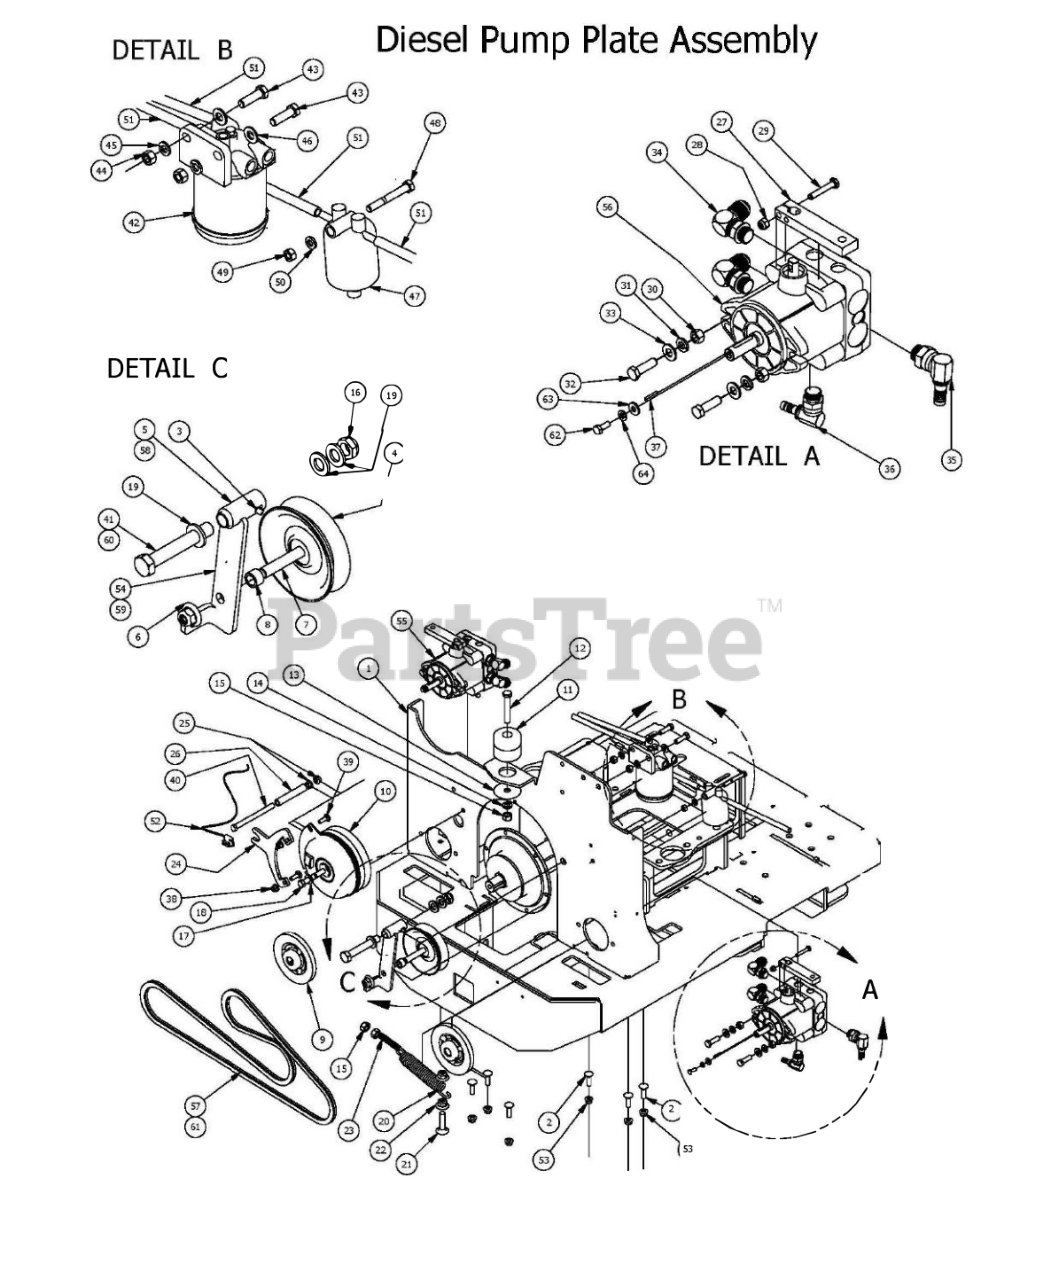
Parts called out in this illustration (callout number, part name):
1	Pump Plate Diesel
2	3/8" x 1 1/4" Carriage Bolt
3	1/4" Drive in Grease Fitting
4	4 3/4" Idler Pulley
5	Pump Idler Bracket only for 61" Deck
6	1/2-13 Nylon Flange Nut-Orange
7	1/2" x 3" Hex Bolt
8	1/2 x 1/2 Spacer
9	5" Pump Pulley
10	Clutch Assembly for Diesel
11	Armor Plated Mount-Rear Mount
12	1/2" x 3" Hex Bolt
13	Snubbing Washer
14	1/2" Lock Washer
15	1/2" Hex Nut
16	5/8" Nylock (1/2 Jam)
17	7/16" Lock Washer
18	7/16" x 2 3/4" Fine Thread Bolt
19	.630 ID x 1.122 OD x .142 THK Plastic Washer
20	Deck Idler Spring
21	1/2 x 2" Carriage Bolt
22	1/2-13 Nylon Flange Nut-Orange
23	1/2-13 x 2-1/2 All Thd Stud
24	Diesel PTO Engager Holder
25	3/8" Flange Nut
26	3/8 hose 4" long
28	1/4" Nylock Nut
29	1/4" x 1 1/2" Bolt
30	3/8" Hex Nut
31	3/8" Lock Washer
32	3/8" x 1 1/2" Hex Bolt
33	3/8" Flat Washer
34	90 Degree Adaptor 6801-L-8-8 Fitting
35	90 Degree Fitting 1/2" x 3/4" 4601-8-8
36	90 Degree Fitting 3/8" X 9/16"-4601-6-6
37	5mm x 1.25" Key
38	5/16" Flange Nut
39	5/16" x 1" Carriage Bolt
40	3/8-16 x 5 Hex Bolt - Grade 5
41	5/8" x 4" Hex Bolt 61" Deck only
42	Fuel Filter
43	3/8" x 1 1/4" Hex Bolt
44	3/8" Hex Nut
45	3/8" Lock Washer
46	3/8" Flat Washer
47	Caterpillar Fuel Bowl Kit
48	5/16" x 2 1/2" Bolt
50	5/16" Lock Washer
51	5/16" fuel line hose
52	Clutch Pigtail
53	3/8" Nylock Flange Nut
54	Pump Idler Assembly Components 3,4,5,6,7,8, only for 61" Deck
55	Left Pump 16cc -AOS Diesel 35Hp Diesel
56	Right Pump 16cc - AOS Diesel 35Hp Diesel
57	Pump Belt for 72" Deck
58	Diesel Pump Idler only on 72" Deck
59	Diesel Pump Idler Assembly Components 3,4,5,6,7,8,9,10 only for 72" Deck
60	5/8 x 5 1/2 Bolt only for 72" Deck
61	Pump Belt for 61" Deck
62	M6-1.0 X 16MM Hex Bolt
63	1/4" Flat Washer
64	1/4" Lock Washer
